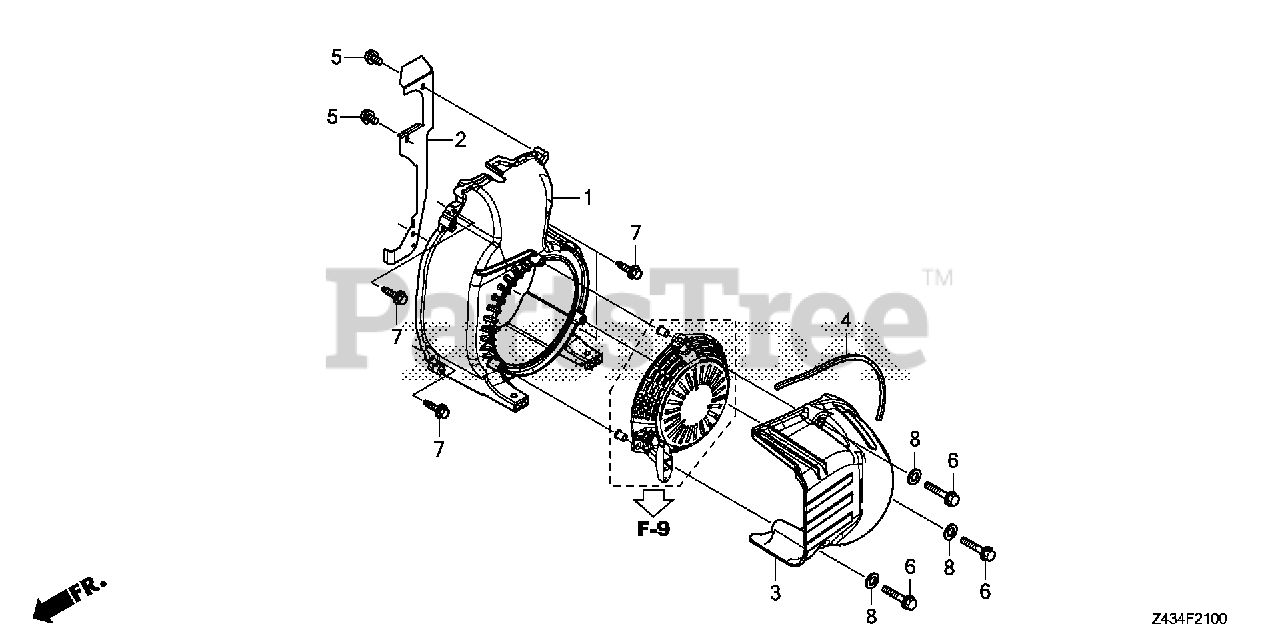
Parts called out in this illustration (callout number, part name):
1	COVER, FAN
2	PLATE A, SIDE
3	GUIDE, AIR *NH1* (BLACK)
4	SEAL, AIR GUIDE
5	BOLT, FLANGE (6X12) (CT200)
6	BOLT, FLANGE (6X28) (CT200) Use up to Engine SN 1530314.
7	BOLT, FLANGE (6X20) (CT200)
8	WASHER (6.5X15)
